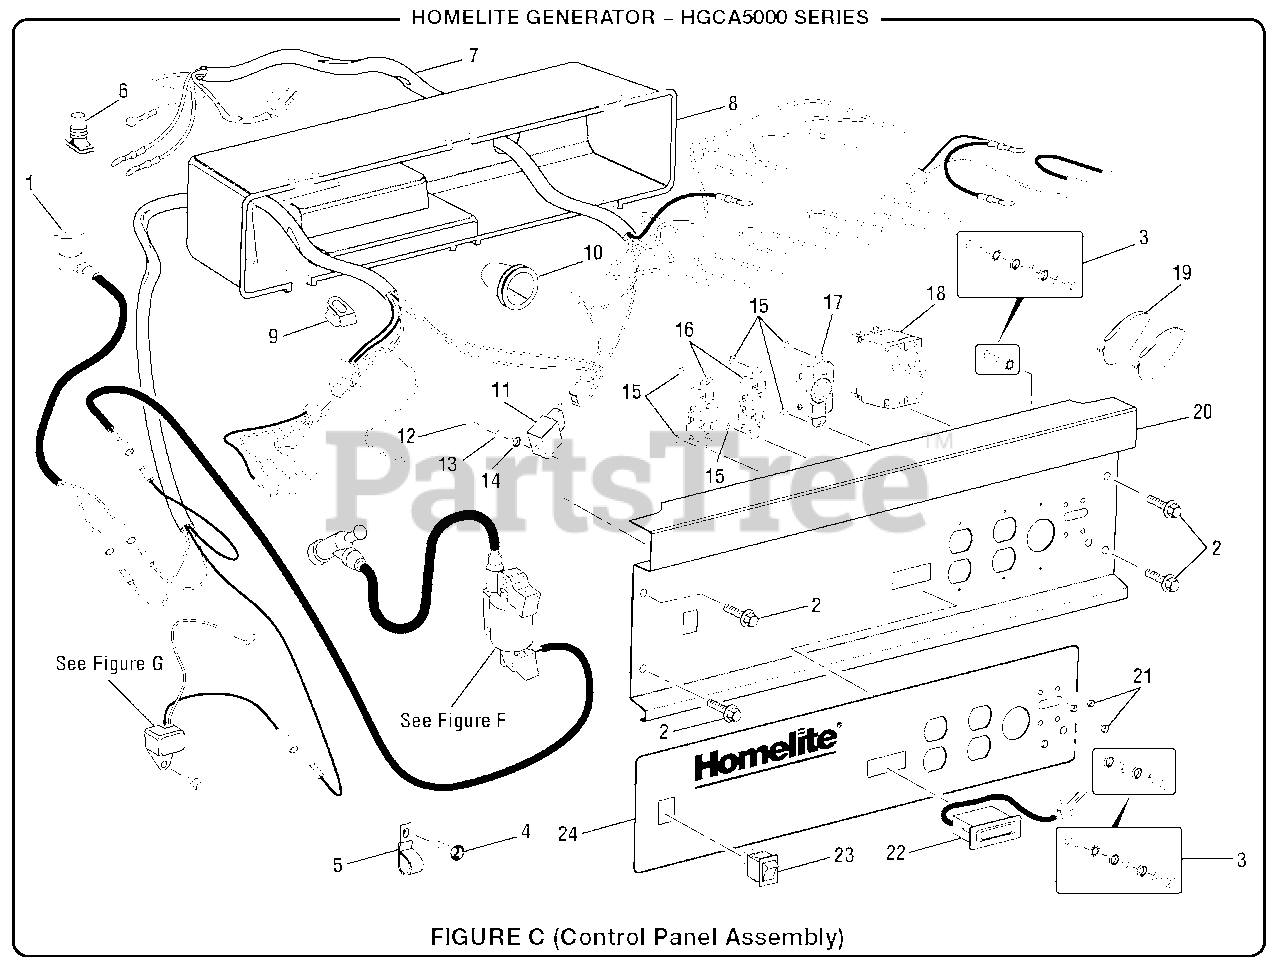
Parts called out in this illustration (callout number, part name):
1	Fuel Valve Solenoid
2	Bolt (M6 x 16 mm)
3	Ground Terminal Assembly
4	Screw (M6 x 12 mm)
5	Wire Clamp
6	Boot, Square
7	Wiring Harness Assembly
8	Cover, Control Panel Box
9	Boot, Switch Wire
10	Boot, Round
11	Diode Assembly
12	Screw (M4 x 15 mm)
13	Lock Washer (M4)
14	Washer (M4)
15	Hex Nut (M4)
16	120 V/ 20amp Duplex Receptacle
17	220 V/ 30amp Twist Lock Receptacle
18	Circuit Breaker, 2 pole 25 amp
20	Control Panel
21	Screw (M3 x 6 mm)
23	Ignition Switch
24	Control Panel Label
